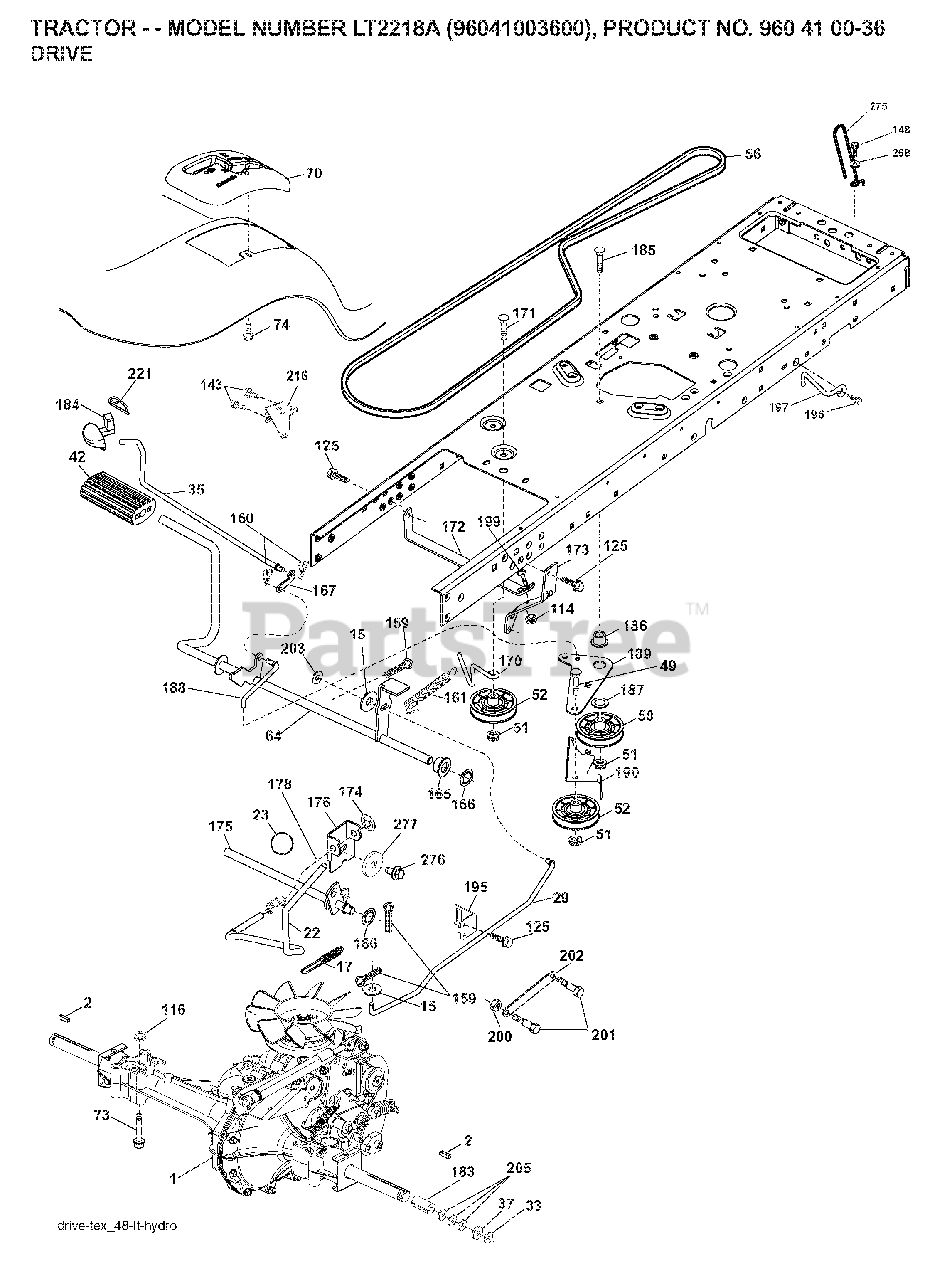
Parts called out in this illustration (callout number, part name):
2	SQUARE KEY
17	SPRING.BRAKE.HG3000/3500
22	ROD.SHIFT.FENDER.TLT.2006
23	PISTOL KNOB
29	ROD.BRAKE.HG-0510
33	E-RING LT
35	ROD.BRKAE.PARKING.STEALTH
42	PEDAL COVER T
49	BOLT
50	IDLER.FLAT.910.OFFSET
51	NUT LOCK FLG 3/8-16 UNC
52	IDLER.V-GROOVE.910.OFFSET
64	SHAFT.ASM.PEDAL.BRAKE.
70	CONSOLE.SHIFT.STL.HYD.BLACK
73	BOLT HEX 5/16-18 GR 5
74	SCREW.HI-LO.CONSOLE
114	NUT.71038.31-18.HEX.NYLOCK
116	NUT LOCK HEX FLANGE 5/16-18
125	SCREW
148	SCREW, 3/8-16X3/4
159	COTTER PIN
160	RETAINER CLIP
161	SPRING.RETURN.CLUTCH.2006
165	BUSHING.SHAFT.BRAKE.HAND
166	NUT.PUSH.625.2006
167	LATCH.BRAKE.SPRING
170	KEEPER.V-IDLER.CENTER.
171	BOLT
172	STRAP.TRQ.LH.FS.HG0510
173	STRAP TORQUE RH
174	NUT.PUSH.500.2006
175	SHAFT.ASM.SHFT.HG0510/
176	ARM.CLEVIS.ROD.SHIFT
178	SPRING.SHIFT.GT2006
183	SPACER AXLE
184	HANDLE.PRKG.BRAKE.STLTH.TX.RED
186	SPACER.RETAINER
187	WASHER 12/32X2X10GA
188	LINK.CLUTCH.GROUND.DRIVE
189	BELLCRANK.GROUND.DRIVE.TEX.
190	KEEPER.BELLCRANK.DRIVE
195	BRKT.ROD.BRAKE.18/20/2
197	LINK.CLUTCH.ANIT-ROTAT
199	BOLT
200	NUT.CENTERLOCK.5/16-
201	BOLT SHOULDER 5/16-18 UNC
203	WASHER
216	BRACKET.PULLEY.IDLER.W/TEX
221	RETAINER.SPRING.CLIP.H
268	WASHER
276	BOLT FIN HEX 7/16-14 X 1
277	WASHER SERRATED
